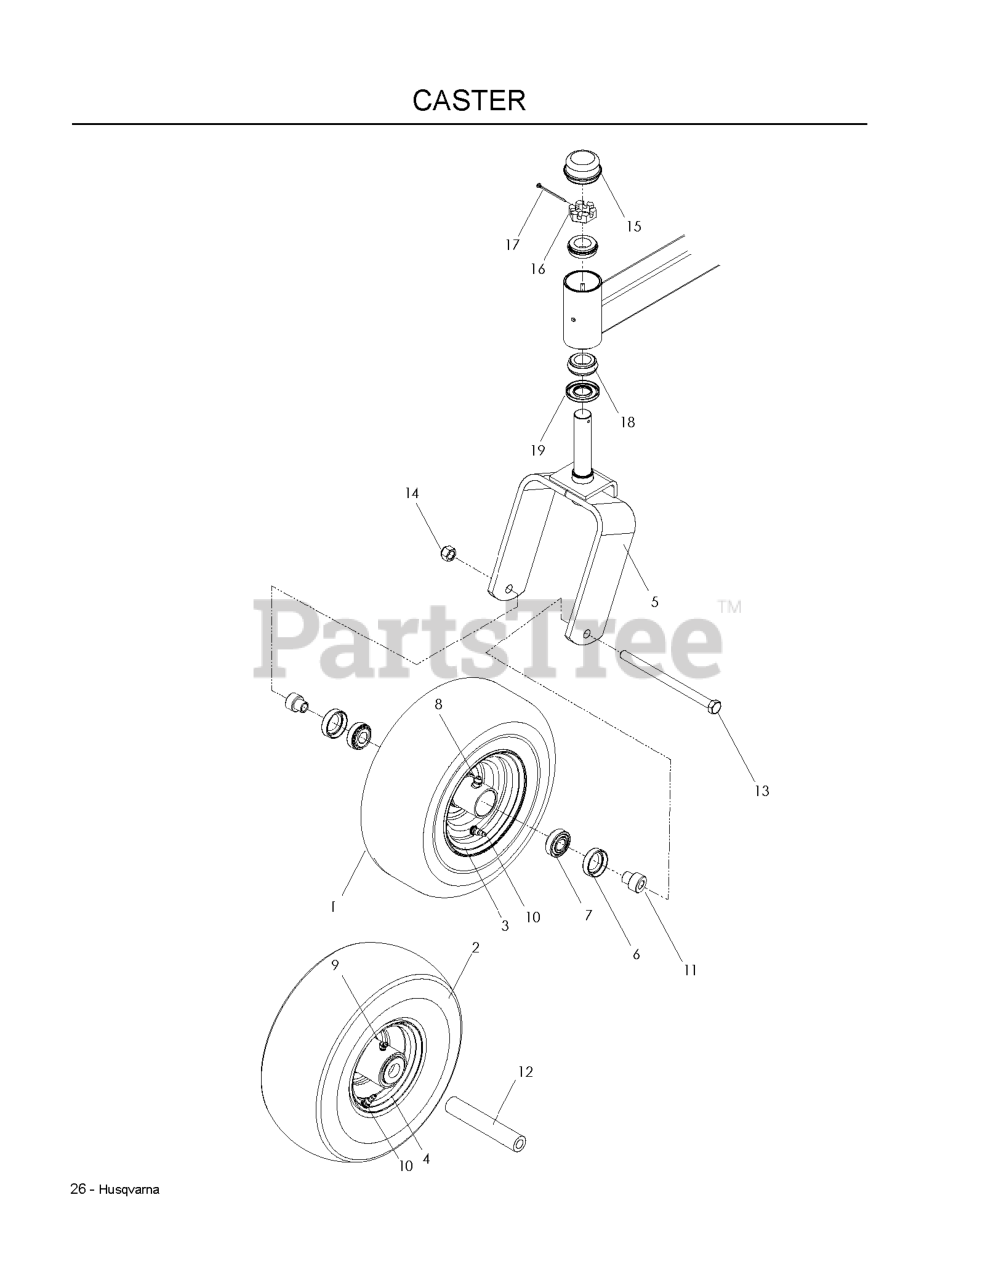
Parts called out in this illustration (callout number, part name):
1	FRONT TIRE ASSY
2	TIRE.ASSEM.13X5-6.SMOOTH.SILVE
4	RIM
5	CASTER YOKE ORANGE
5	CASTOR YOKE ORANGE
6	TAPERED BEARING W/RACE
7	ZERK
8	ZERK 1/8 NPT
9	VALVE STEM TR-412
10	AXLE SPACER
11	SPACER, CASTER
12	HEX SCREW 1/2-13 X 9.5 GR5
13	SCREW 1/2C X 7 1/2 HEX CAP
14	NUT 1/2-13 HEX NYLOC ZD
15	GREASE CAP
16	NUT 1"C HEX SLOTTED
17	COTTER PIN 1/8 X 2
18	TAPERED ROLLER BRG
